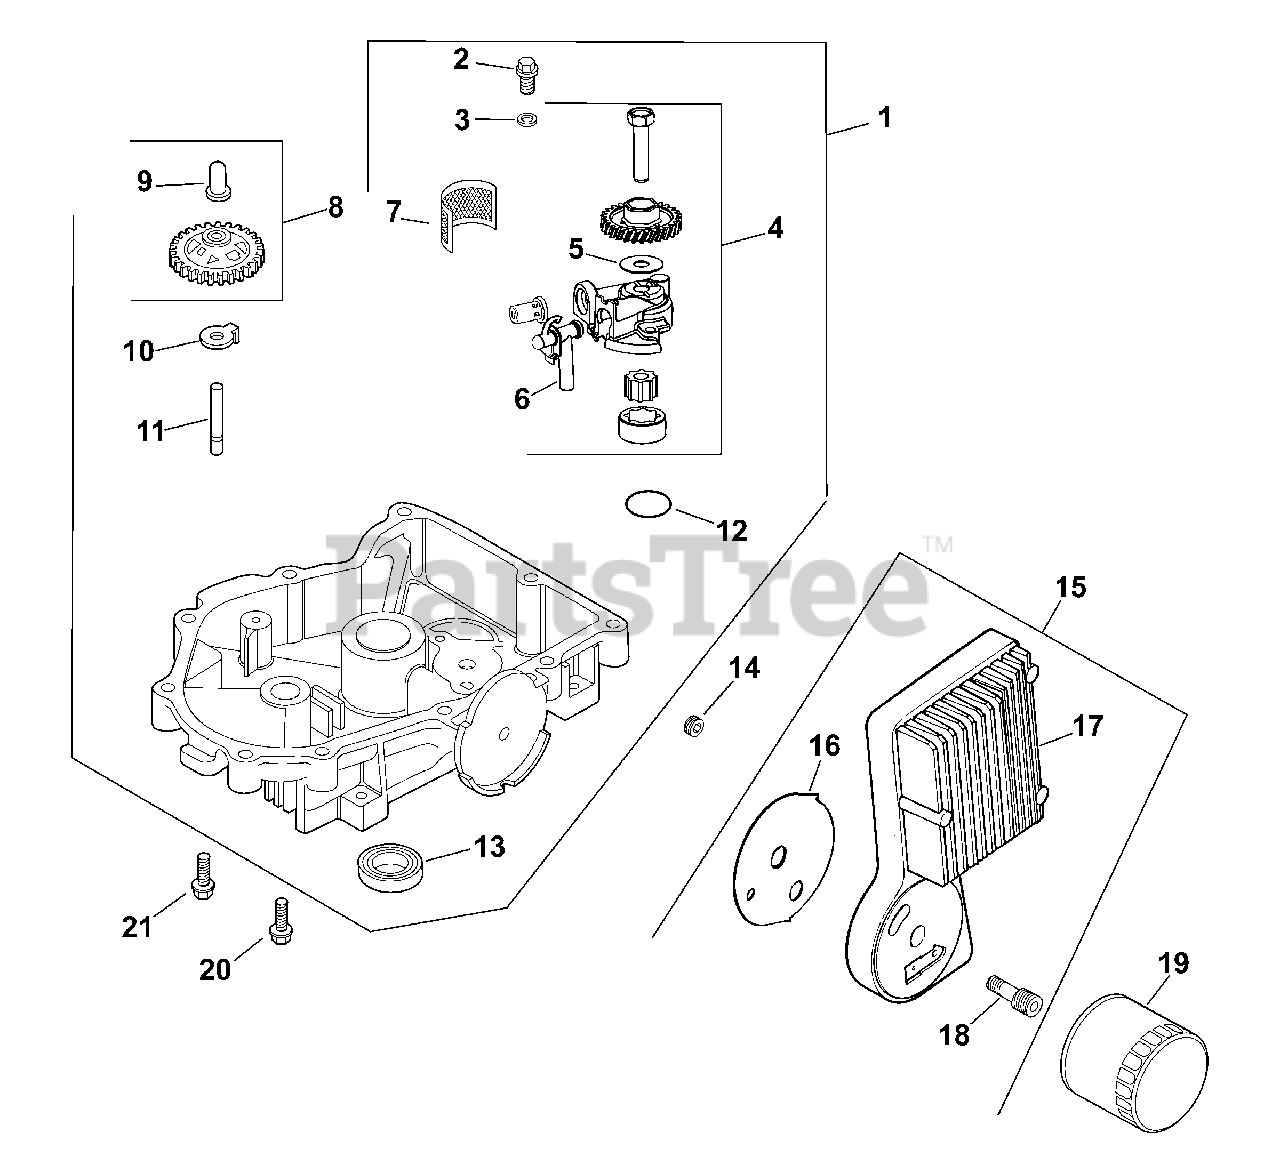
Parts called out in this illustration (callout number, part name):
1	PAN , OIL ASSEMBLY USE 24 199 32-S
2	SCREW,FLG THD FRM M6X1.0X25-(#25086395S)
3	WASHER, FLAT 6 MM
4	OIL PUMP ASSY KIT-USE 24 393 53-S
5	O-RING, OIL PICK-UP
6	KIT, OIL PICK-UP TUBE
7	SCREEN, OIL
8	KIT, GOVERNOR GEAR W/PIN
9	PIN, GOVERNOR REGULATING
10	TAB, LOCKING
11	SHAFT, GOVERNOR GEAR
13	SEAL, OIL (KM)-USE 25 032 06-S
14	PLUG, SQ HD PIPE 3/8"
15	KIT, OIL COOLER
16	GASKET, OIL FILTER ADAPTER USE 24 041 88-S
17	COOLER, OIL ASSEMBLY
18	NIPPLE, OIL FILTER
19	OIL FILTER
20	SCREW, HEX FLANGE -USE 24 086 17-S
21	SCREW, FLG M8X1.25X45
